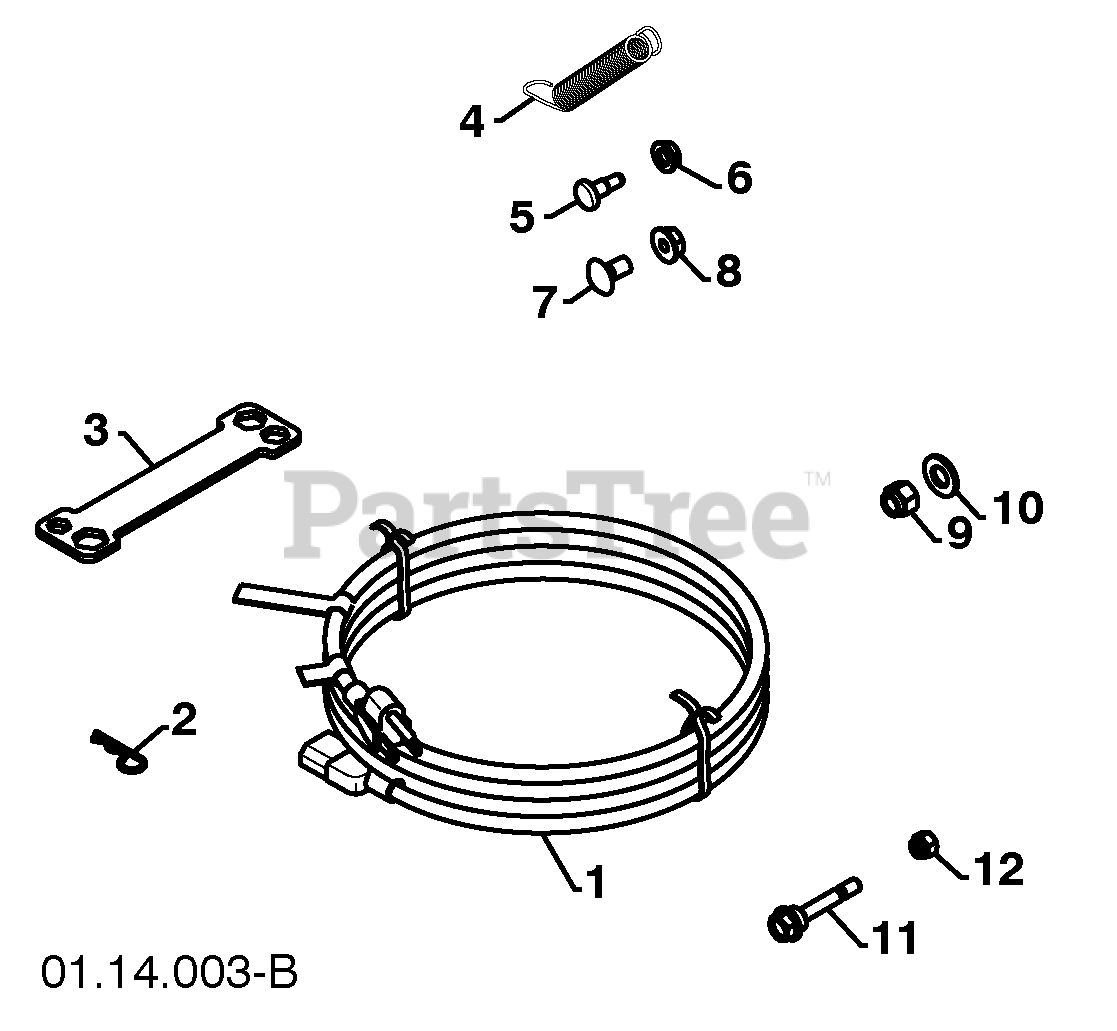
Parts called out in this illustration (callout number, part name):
1	POWER CORD
2	RETAINER PIN
3	WRENCH
4	REMOTE SPRING
5	SHOULDER BOLT 1/4-20
6	LOCKNUT 1/4-20
7	CARRIAGE BOLT 5/16-18 X 5/8
8	LOCKNUT 5/16-18
9	LOCKNUT 3/8-16
10	WASHER 3/8
11	SHEAR BOLT 1/4-20 X 1-13/16
12	LOCKNUT 1/4-20
